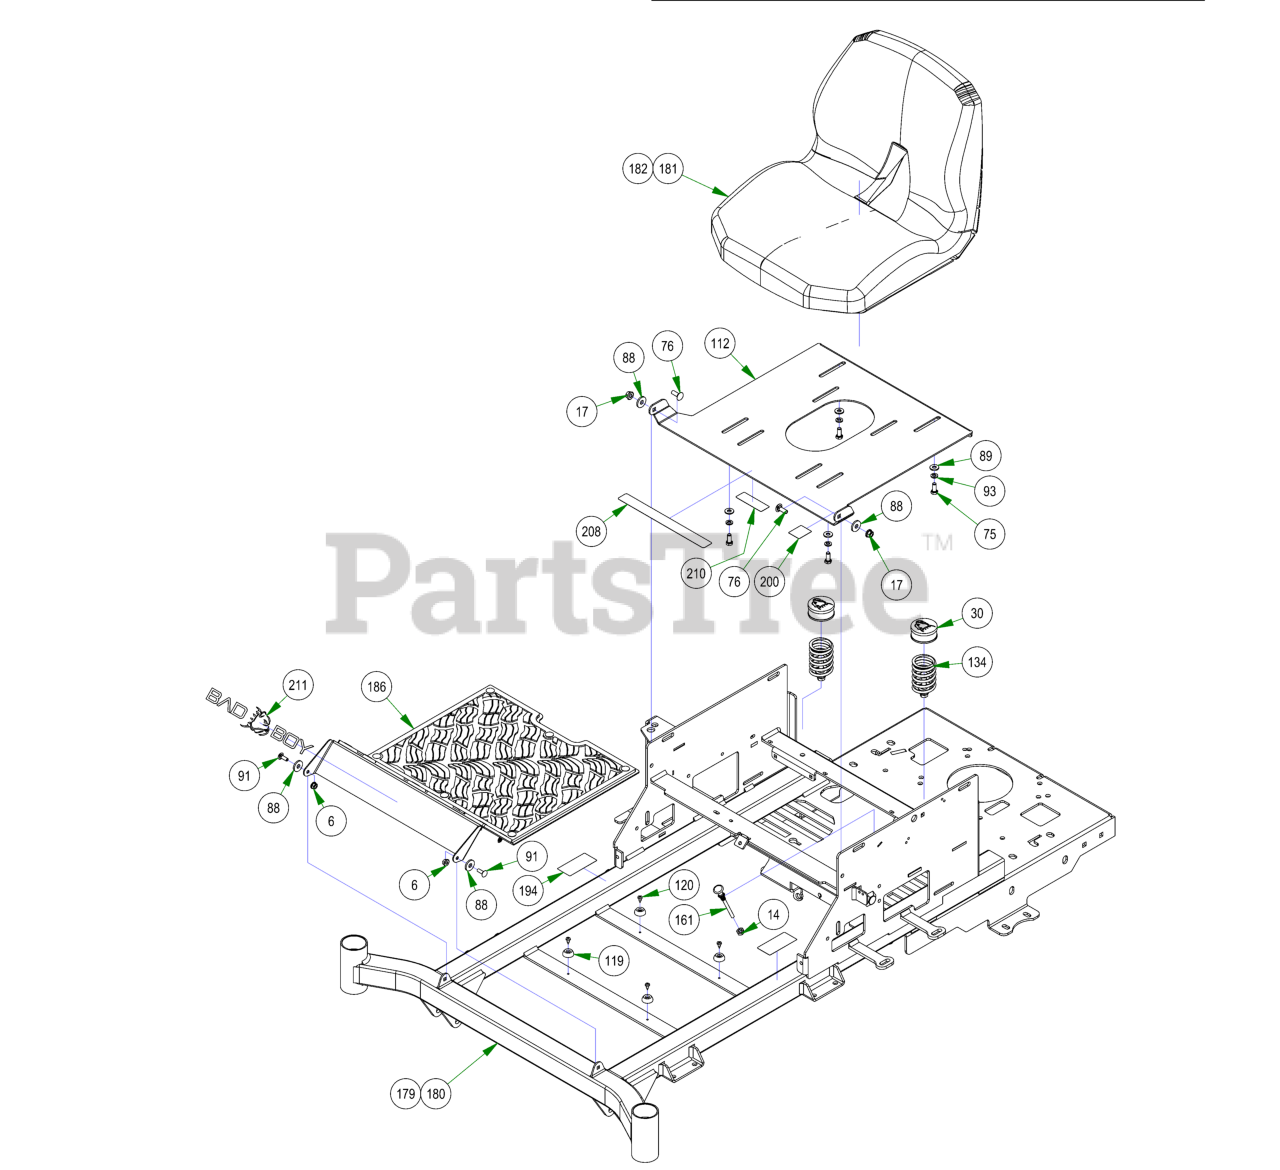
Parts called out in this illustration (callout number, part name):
6	1/4-20 NYL INSERT FLANGE LOCKNUT ZINC
14	3/8-24 HEX NUT ZINC YELLOW
17	5/16-18 NYLON INSERT FLANGE LOCKNUT ZINC
30	Spring Cap Cover
75	5/16-18 X 3/4 HEX CAP SCREW (GR.5) ZINC
76	5/16-18 X 7/8 CARRIAGE BOLT ZINC
88	.360 ID X .983 OD X .120 THICK FLAT WASHER NYLON
89	1/4 USS FLAT WASHER (3/4 OD) ZINC
91	1/4-20 X 3/4 CARRIAGE BOLT (GR.5) ZINC
93	5/16 SPLIT LOCKWASHER ZINC
112	2017 MZ Seat Plate
119	Button Bumper
120	10-16 X 1/2 PAN PHIL TEK/3 CLIMASEAL OR ACF-SILVER COATED
134	Seat Spring Assembly
179	2022 MZ/ZT 54"-60" Frame
180	2022 MZ/ZT 42"-48" Frame
181	2019 Magnum Seat/Kohler
182	2022 Magnum Seat
186	2020 MZ AVEN Floorboard Assembly
194	2018 LH/RH Steering Control Decal Roll
200	2018 MZ/Magnum/ZT/MAV/Comp Out Brake Decal
208	Outlaw Warning Decal
210	Not For Sale In California
211	Flying Bulldog Front Bumper Decal
